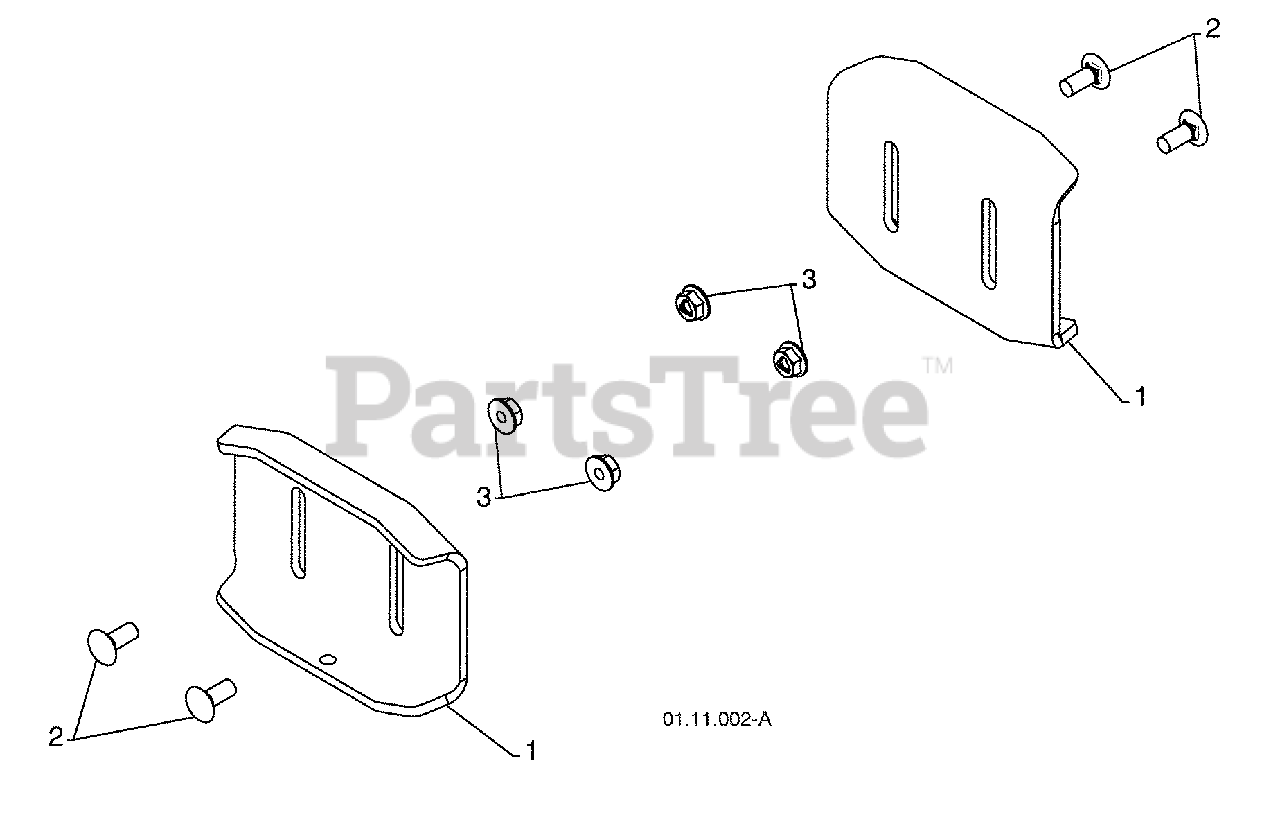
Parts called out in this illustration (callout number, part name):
1	SKID PLATE
2	CARRIAGE BOLT 5/16--18 X .750
3	NUT 5/16--18
